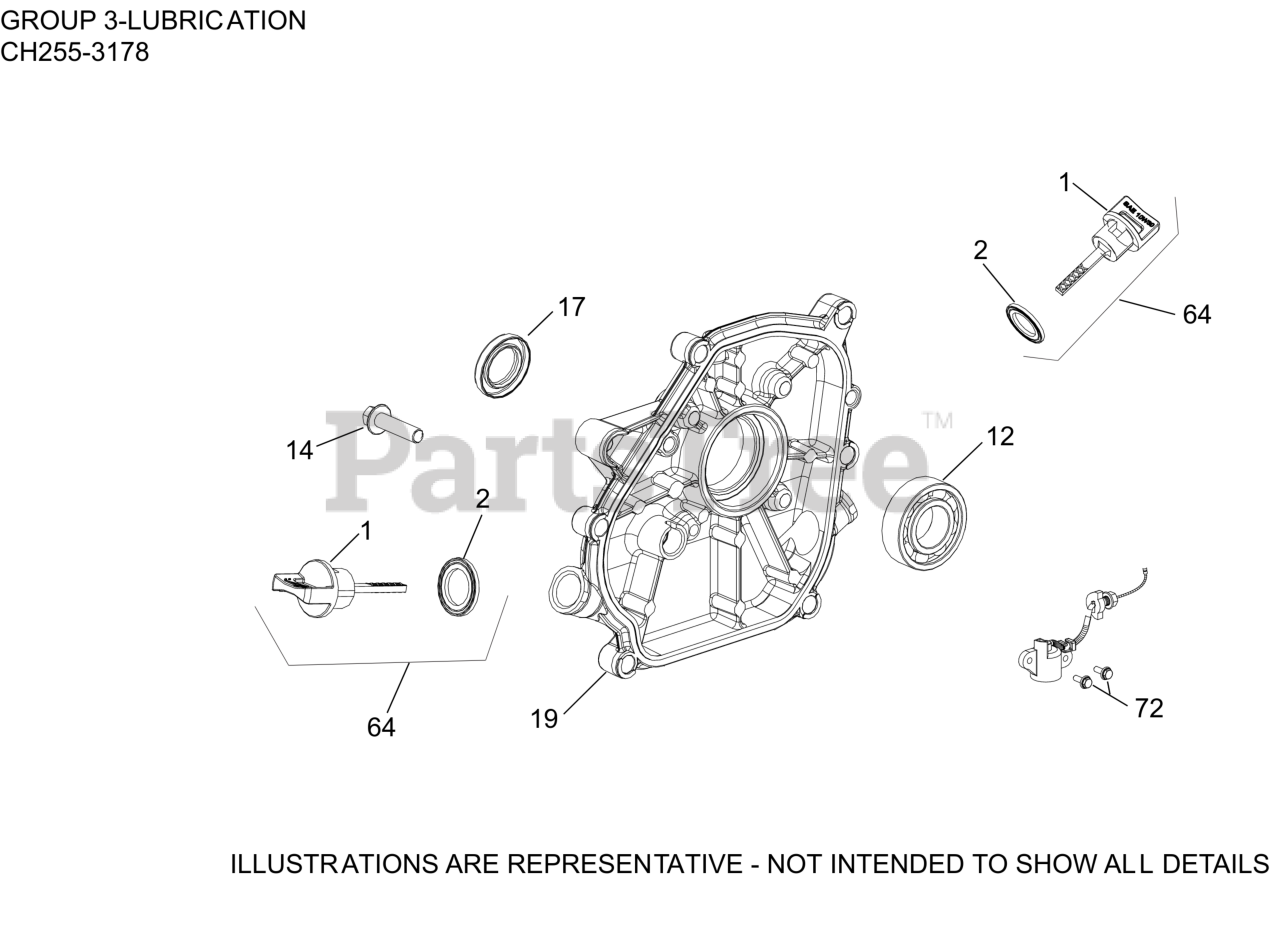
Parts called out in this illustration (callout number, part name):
1	DIPSTICK - USE 17 038 08-S
2	SEAL, DIPSTICK
12	BEARING, BALL
14	SCREW, CLOSURE PLATE
17	SEAL - USE 17 032 29-S
19	PLATE, CLOSURE & BEARING
64	DIPSTICK ASSEMBLY
72	SCREW, M6 X 16
